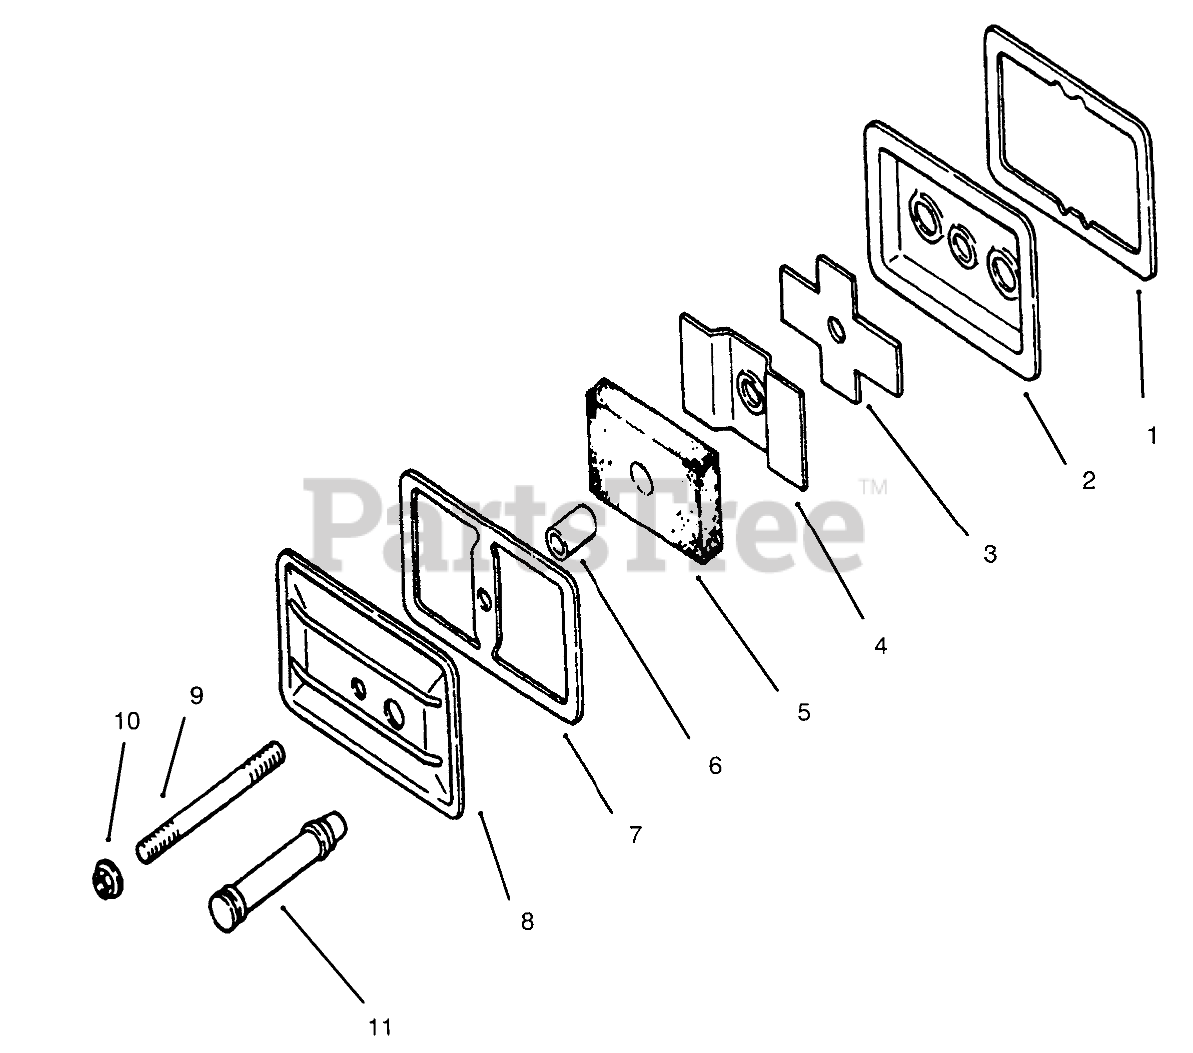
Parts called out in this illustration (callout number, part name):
1	Gasket
2	Plate
3	Reed
4	Baffle
5	Filter
6	Seal
7	Gasket
8	Cover
9	Stud
10	Palnut
11	Hose
